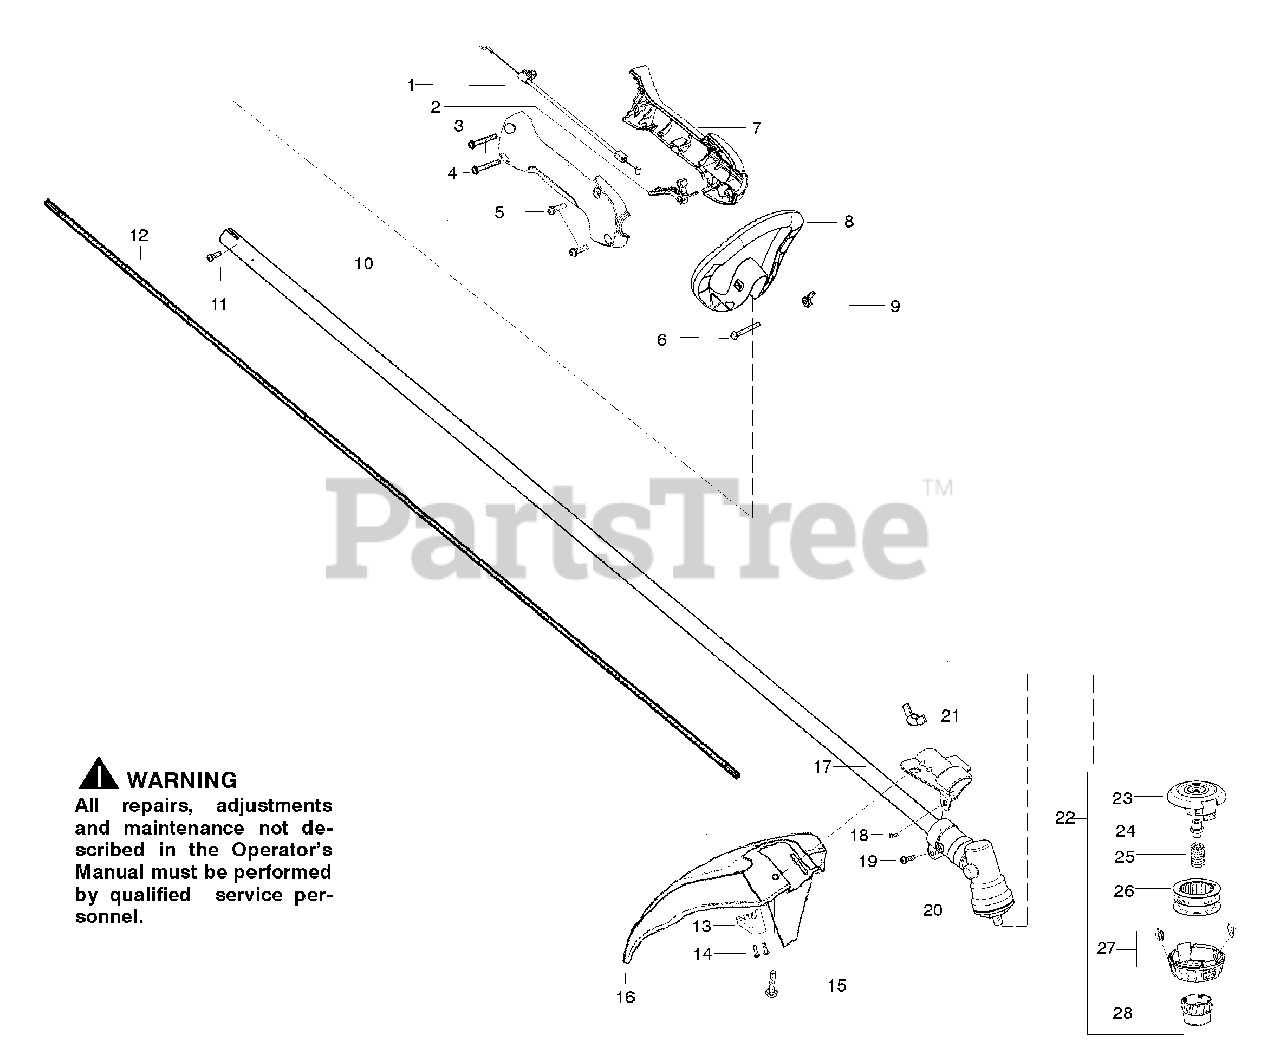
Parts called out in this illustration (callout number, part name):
1	Assy-Throttle Cable
3	Throttle Hsg.
6	Bolt-Handle
7	Throttle Hsg.
8	Assy-Handle
9	Wingnut-Handle
10	Assy-Drive Shaft Hsg.
11	Screw
12	Shaft- Flex
13	Line Limiter
15	Bolt-Shield
16	Kit-Shield Assy
17	Bracket-Shield
20	Assy-Gearbox
21	Wingnut
22	Assy - TNG7 Head
26	Accy-Wound Spool
27	Kit-Cover and Eyelet
